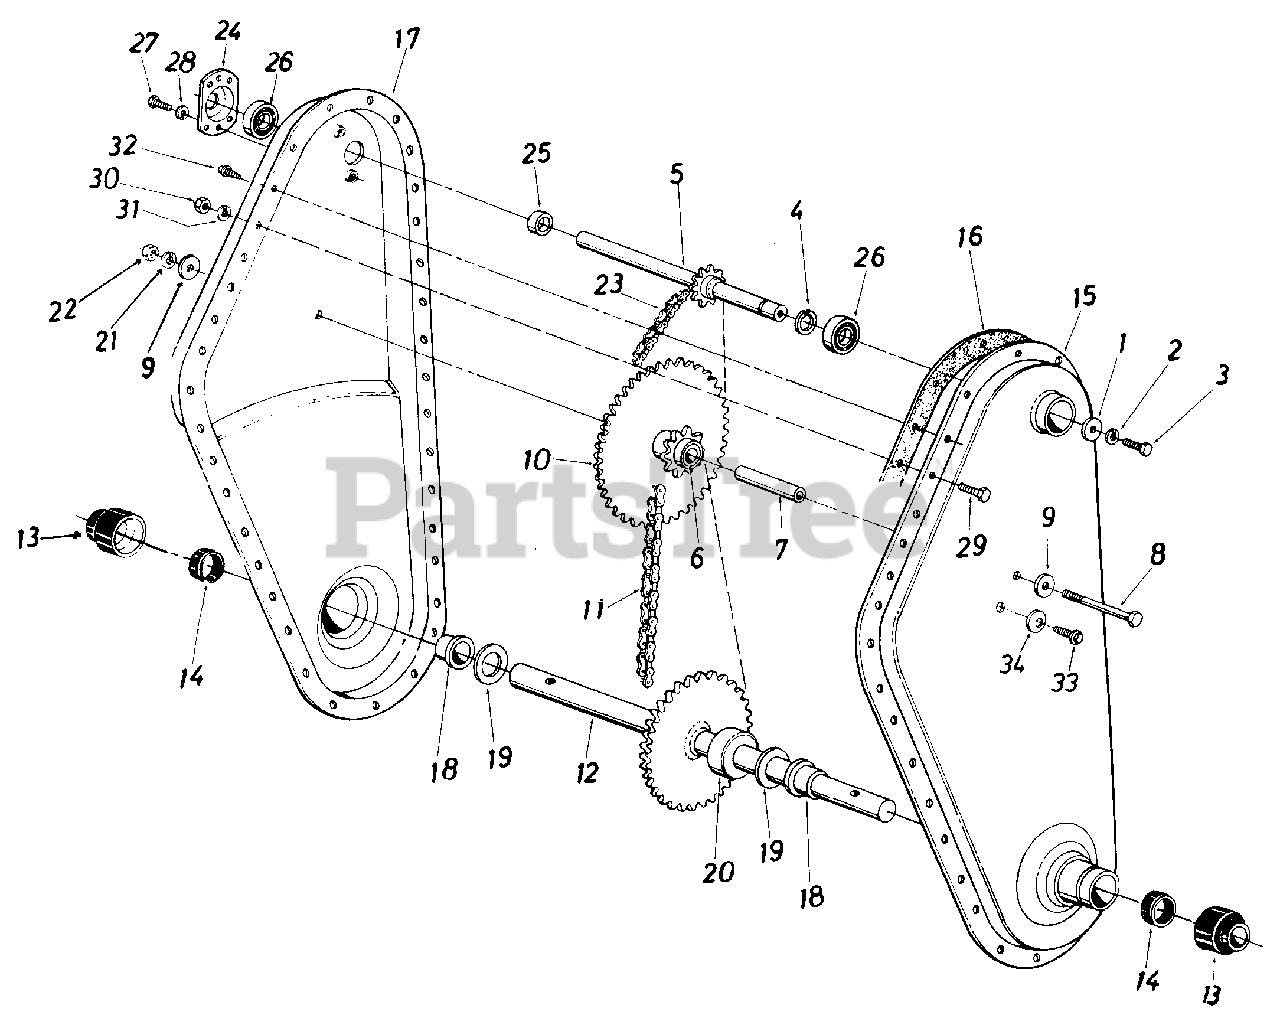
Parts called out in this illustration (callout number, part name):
1	Fl-Wash. 1/4" I.D. x .93" O.D.
2	L-Wash. 1/4" I.D.
3	Hex Bolt 1/4-28 x .62" Lg. w/ Patch
4	External Snap Ring-5/8" Dia.
5	Input Shaft Ass'y.
6	Bearing 5/8" I.D. x 3/4'1 O.D. x 1.860" Lg.
7	Sprocket Hub Tubing 3/8" I.D. x 5/8n O.D. x 1.90
8	Hex Bolt 3/8-24 x 2.751' Lg.
9	Fl-Wash. 3/8" I.D. x 1.25"
10	Sprocket Ass'y.
11	#50 Chain 5/8" Pitch x 46 Links Endless
12	Tine Shaft Ass'y.
13	Dust Cup
14	Seal Ring Single Lip
19	Fl-Thrust Wash. 1.0" I.D. x .03 Thk.
20	Step Spacer
21	L-Wash. 3/8" I.D.
22	Hex Nut 3/8-24 Thd.
23	#35 Chain 3/8" Pitch x 52 Links Endless
24	Bearing Housing 1.38" I.D.
25	Spacer
26	Ball Bearing .625" I.D. x 1.38" O.D. x .437
27	Hex Wash. SF-Tap Scr. 1/4-20 x .50" Lg.
28	L-Wash. 1/4" I.D.
29	Hex Bolt 5/16-18 x .75" Lg.
30	Hex Nut 5/16-18 Thd.
31	L-Wash. 5/16" I.D.
32	Hex Wash. SF-Tap Scr. 1/4-20 x .50" Lg.
33	Hex Wash. Hd. Tap Scr. 1/4-20 x .38" Lg.
34	Bell-Wash. .265" I.D. x .75"
